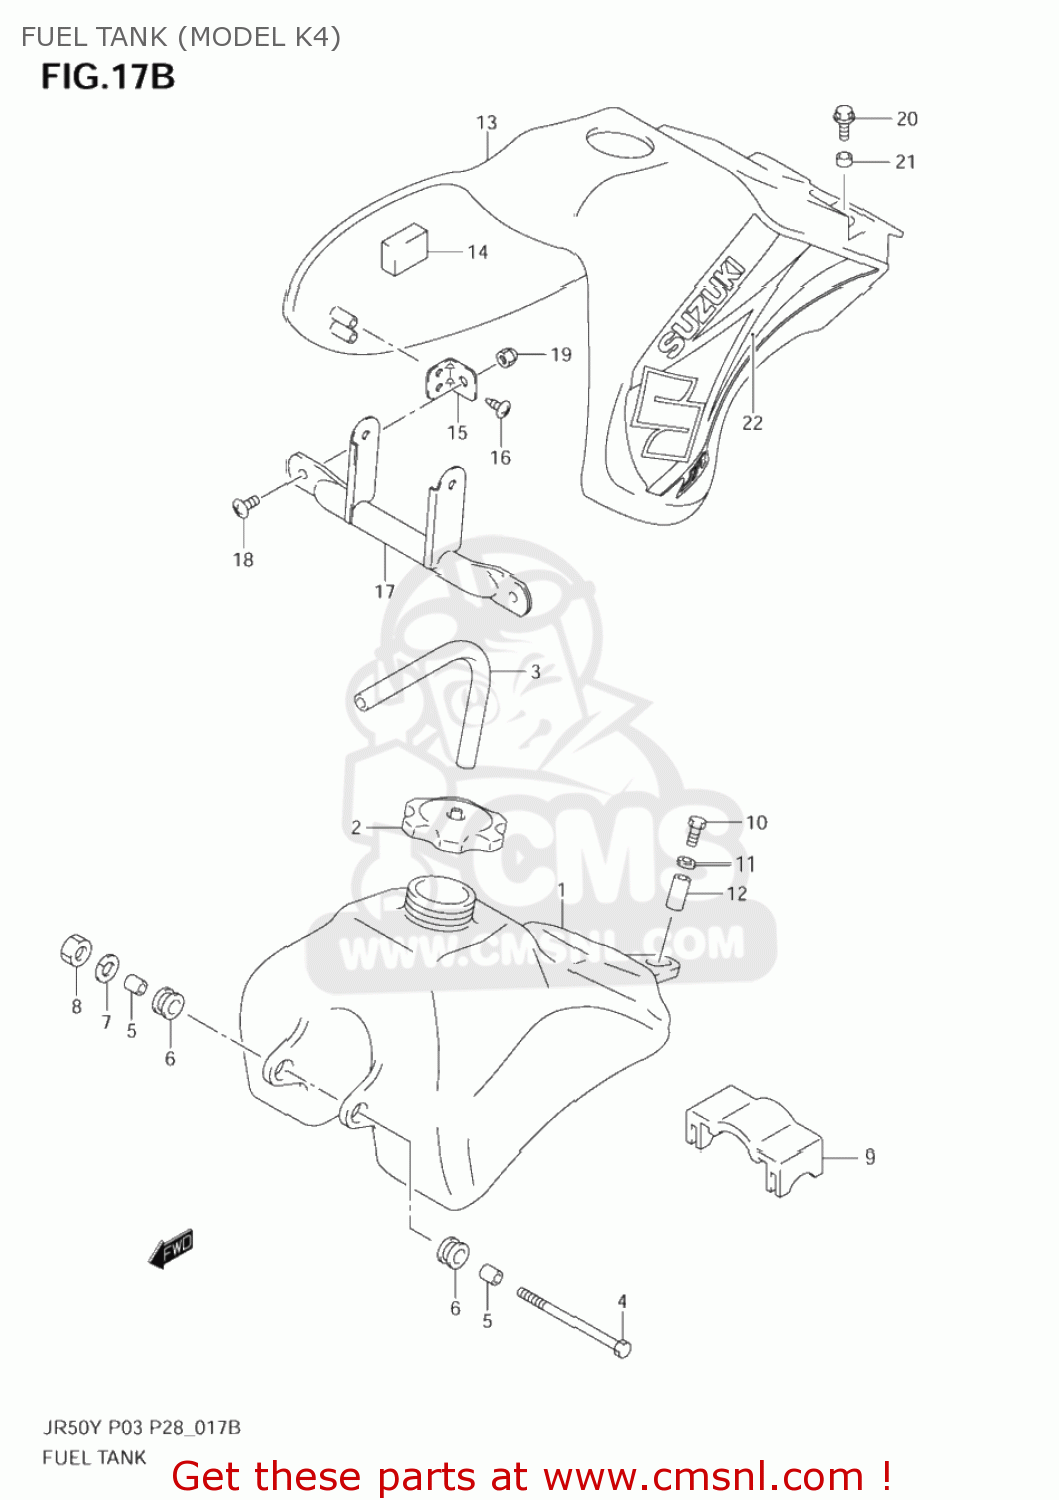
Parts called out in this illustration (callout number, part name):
1	TANK ASSY,FUEL
2	CAP ASSY,FUEL TANK FILLER
3	HOSE(5X8.2X600)
4	BOLT, FRONT
5	SPACER(6.5X10X11.5)
6	CUSHION
7	LOCK WASHER
8	NUT 6MM
9	CUSHION,FUEL TANK UPR
10	BOLT
11	WASHER(6.5X18X1)
12	SPACER(6.5X9X7.2)
13	COVER,FUEL TANK
14	CUSHION,RADIATOR COVER FR
15	BRACKET,FUEL TANK COVER NO.1
16	SCREW
17	BRACKET,FUEL TANK COVER
18	SCREW 6X12
19	NUT
20	SCREW(6X16)
21	SPACER(6.5X10X5)
22	TAPE SET,FUEL TANK COVER
